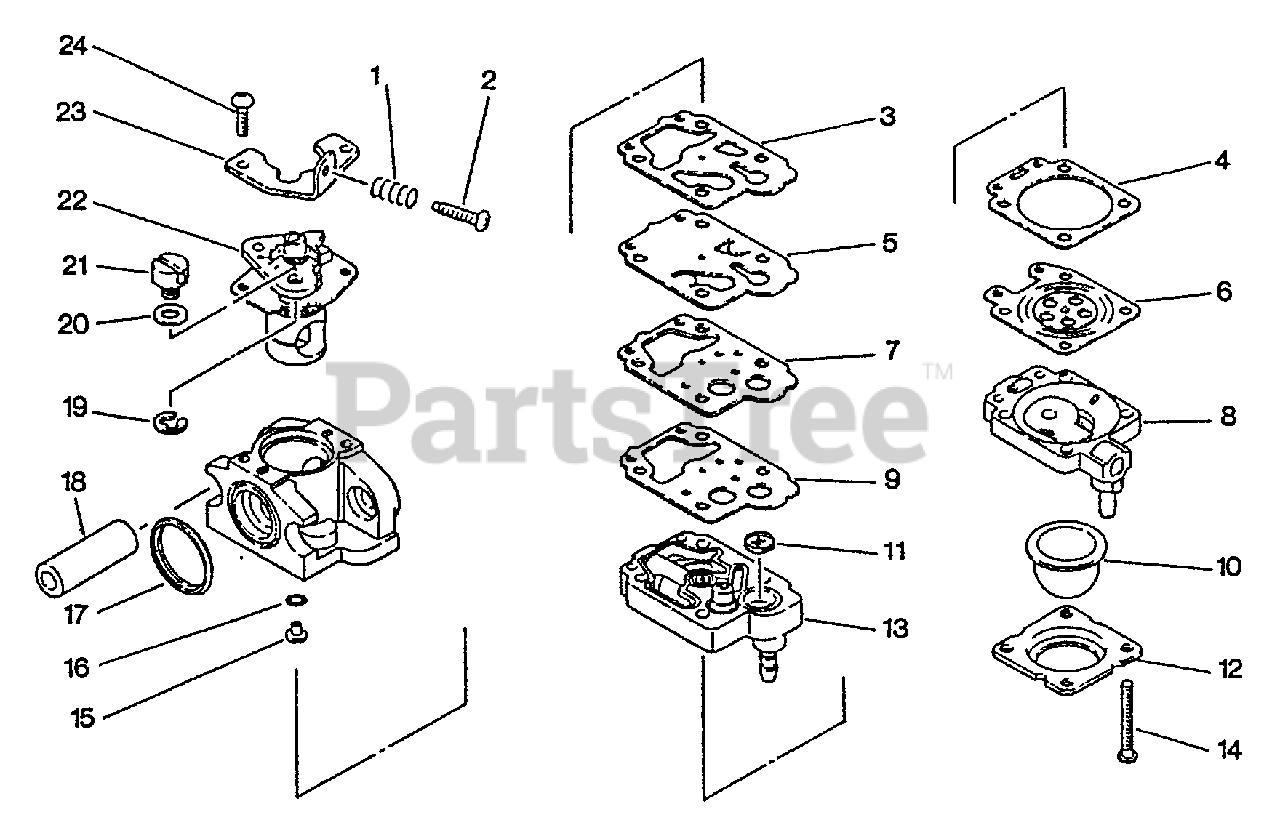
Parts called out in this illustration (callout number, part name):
3	GASKET, PUMP
5	DIAPHRAGM, PUMP
6	DIAPHRAGM, METERING
7	COVER, PUMP
8	BASE, PURGE
9	GASKET, PLATE
10	BULB, PURGE
11	BASE, PURGE
12	RETAINER, PURGE BULB
13	BASE, PURGE
15	BASE, PURGE
16	BASE, PURGE
17	SEAL
18	SLEEVE, MOUNTING
22	VALVE, THROTTLE
23	BRACKET, IDLE ADJUST
A	REPAIR KIT, CARBURETOR
B	DIAPHRAGM KIT
